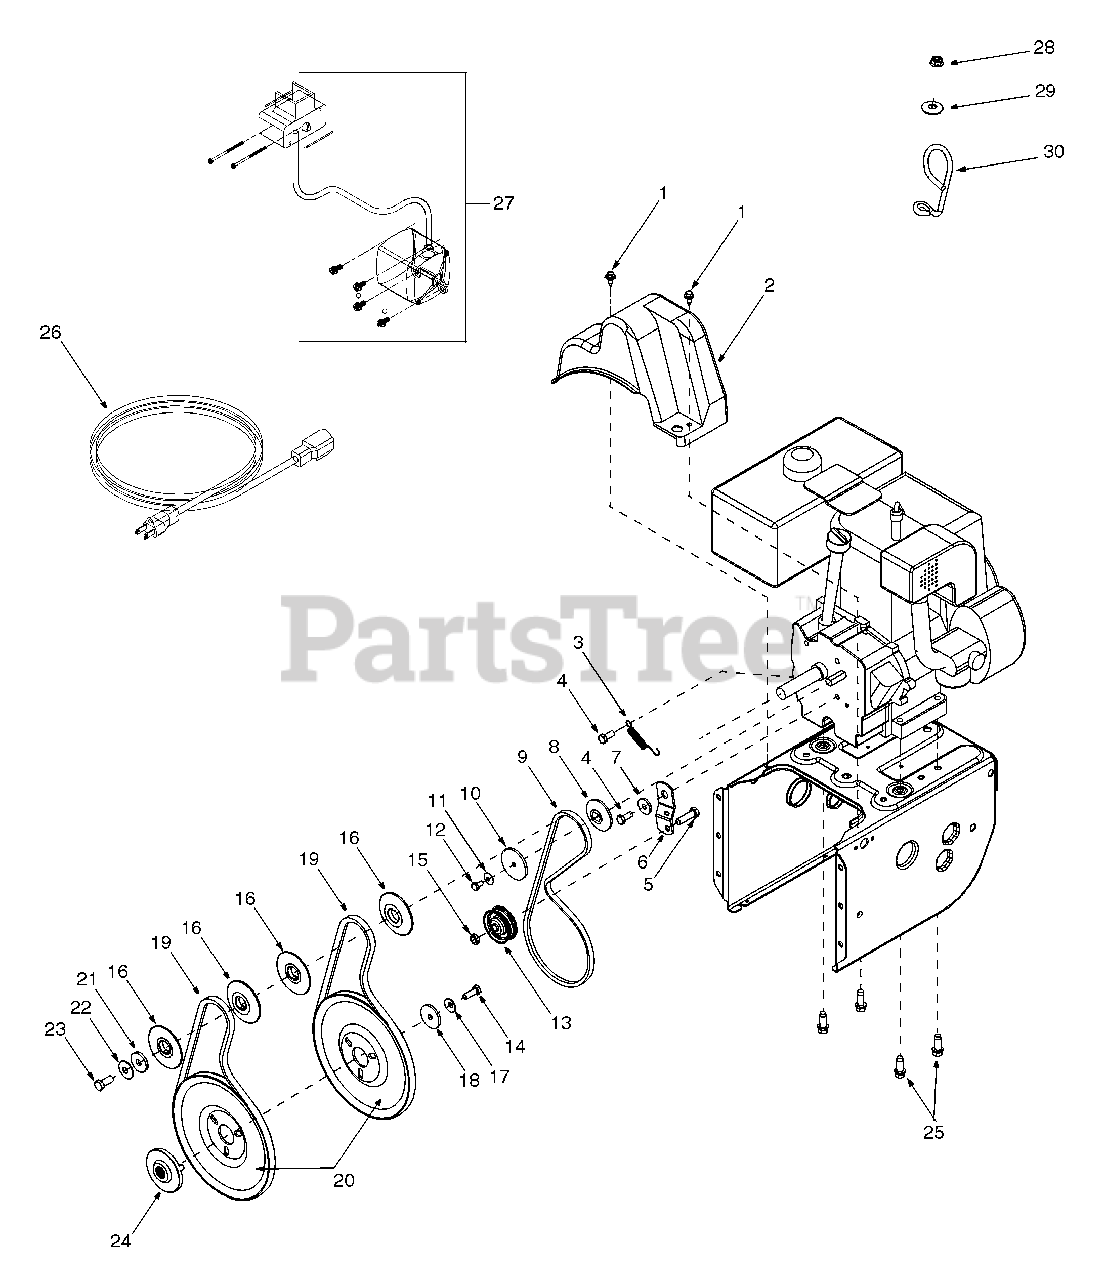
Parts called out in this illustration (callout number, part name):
1	Hex Washer Screw 1/4-20 x .625
2	Belt Cover
3	Extension Spring
4	Hex Screw 5/16-24 x .75
5	Hex Cap Screw 3/8-16 x 1.25
8	Pulley Half
9	V-Belt
10	Pulley Half
11	Bell Washer
12	Hex Cap Screw 1/4-28 x .50
13	Flat Idler
14	Lock Hex Cap Screw 5/16-24
15	Lock Jam Nut 3/8-16
16	Pulley Half
17	Bell Washer
18	Flat Washer
19	Belt
20	Auger Pulley
21	Flat Washer 3/8 x 1.25 OD
22	Bell Washer
23	Hex Cap Screw 3/8-24
24	Adapter Pulley
25	Hex Screw 3/8-16 x 1.0
26	Extension Cord
27	Electric Start Kit
28	Lock Nut, 1/4-20
29	Flat Washer, .28 x .74 x .063
30	Cable Guide
